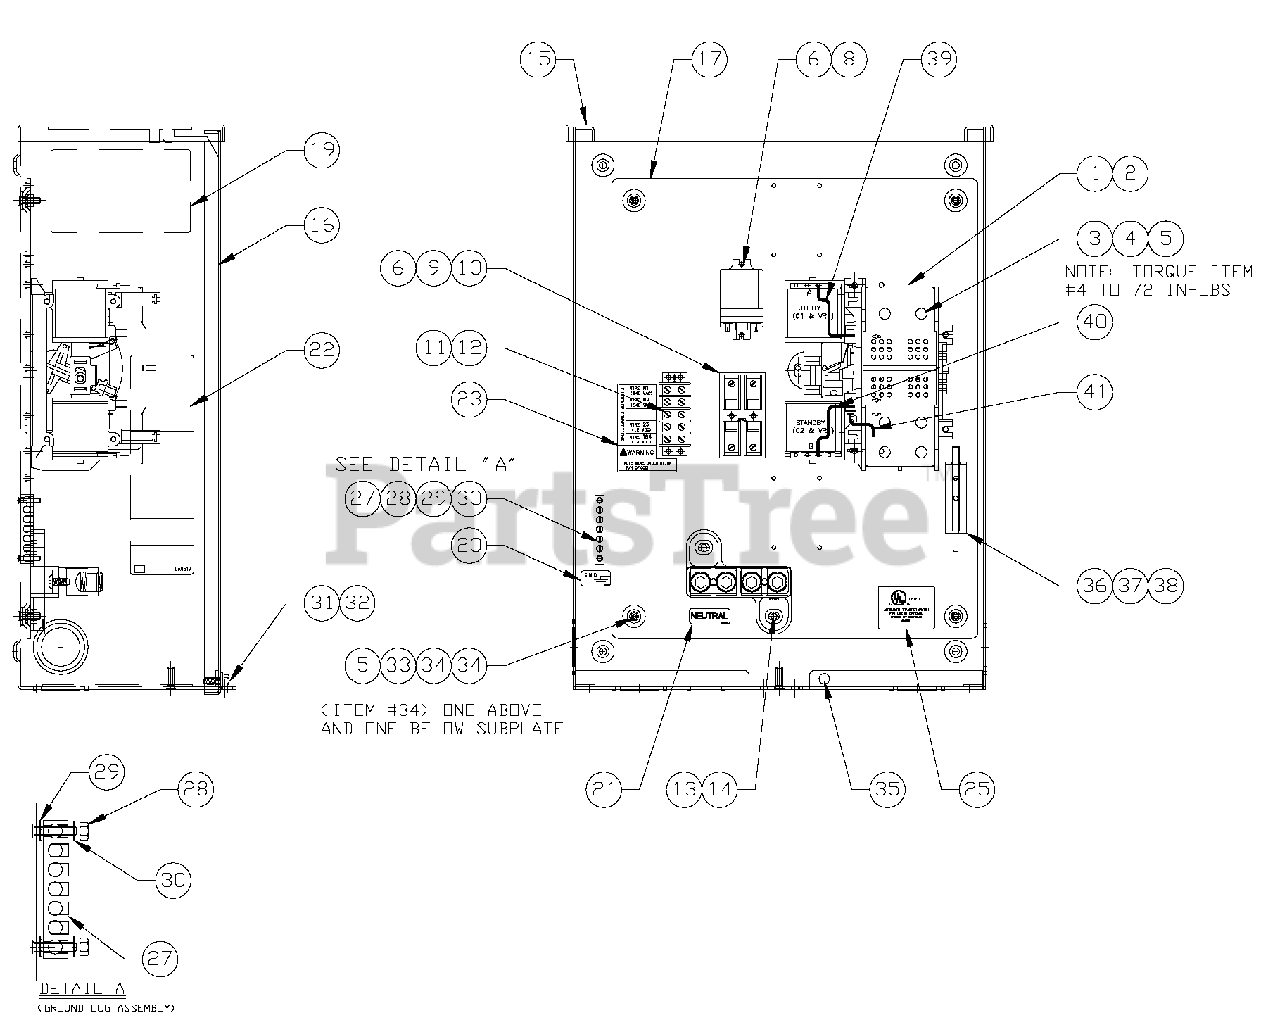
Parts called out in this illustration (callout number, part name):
1	XFRSW HSB 200A 2P 250V
2	SCREW HHTT M5-0.8 X 10 BP
3	LUG SLDLSS 250-#6 AL/CU
4	SCREW BHSC 1/4-20 X 3/8
5	WASHER LOCK M6-1/4
6	SCREW HHTT M4-0.7 X 10 BP
8	RELAY PNL 12VDC DPDT
9	FUSEBLOCK 30A 600V 2 POLE
10	FUSE 5A X BUSS HLDR73591
11	BLOCK, TERM 20A 5 X 6
12	RIVET, POP .156 X .67
13	ASSY NEUTRAL BL150-200A
14	SCREW HHTT M6-1.0 X 12 MM
15	ENCLOSURE, 100/200A TRANSFER SWITCH
16	COVER, TRANSFER SWITCH
17	SUBPLATE, 100/200A XFER SW
18	DECAL, FRONT COVER ATS NEMA3R
19	DECAL,XFER SW NON 200A 120/240
20	DECAL, GROUNDING LUG
21	DECAL, NEUTRAL
22	DECAL, MANUAL 5A FUSE
23	DECAL, TERMINAL STRIP
25	DECAL, UL LIST HSB
27	GROUND BAR (5) 4-14 AWG CONN
28	NUT HEX LOCK M4-0.7 SS NYL INS
29	WASHER SHAKEPROOF EXT #8 STEEL
30	WASHER FLAT M4
31	SCREW HHC 1/4-20 X 1/2 SS
32	WASHER M6 NYLON INT HEX
33	NUT HEX 1/4-20 SS
34	WASHER FLAT 1/4-M6 ZINC
35	NUT TRIC 1/4-20 X .525
36	BRACKET, ARM EXTENDER
37	ARM EXTENDER PIN
38	RIVET POP .156 X .362 AL
41	WIRE-E1
